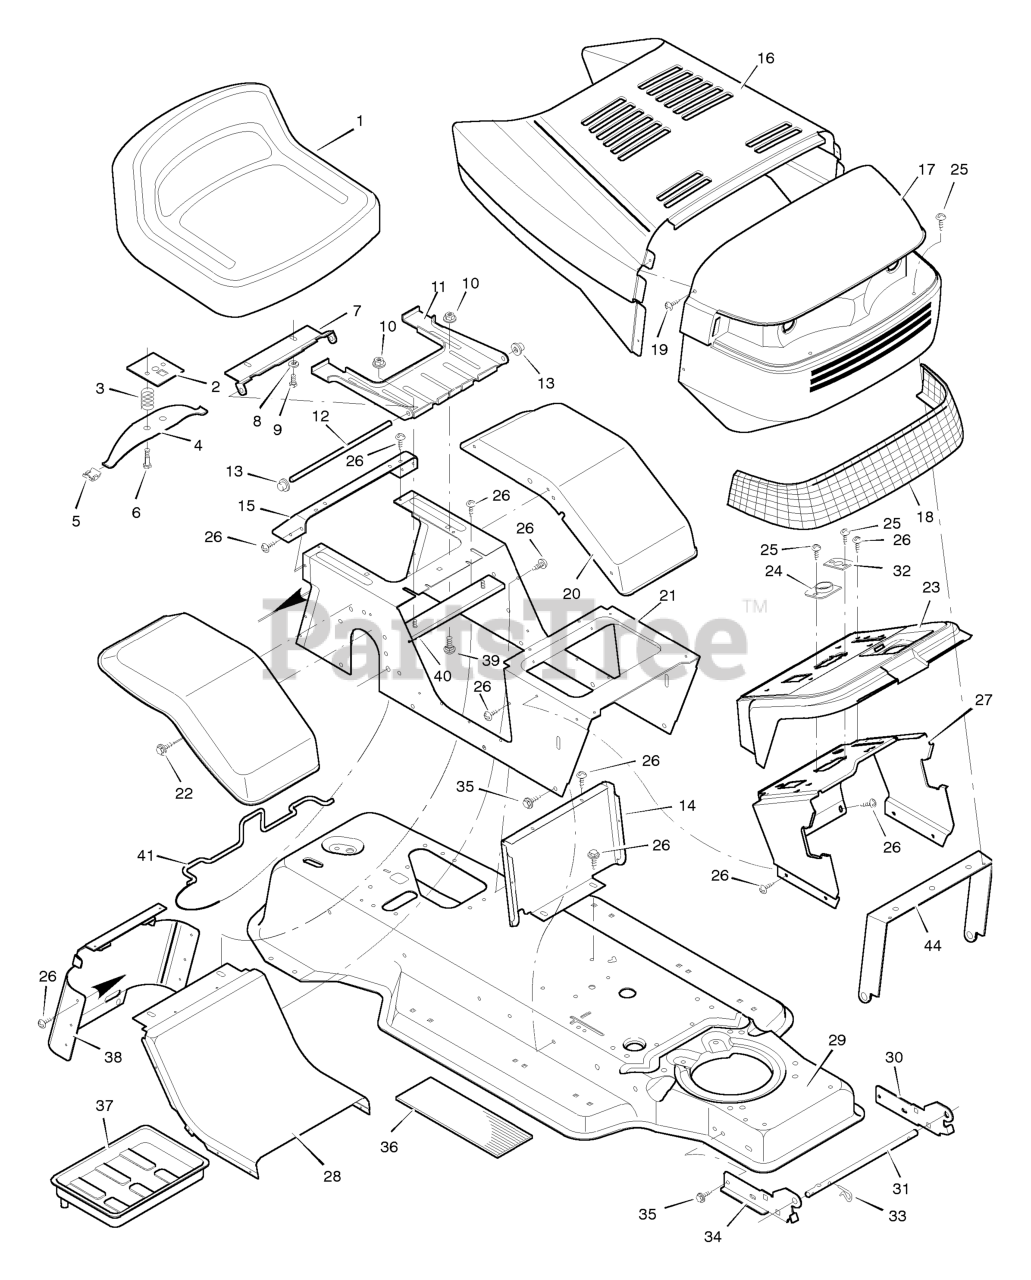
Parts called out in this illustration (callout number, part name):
2	Plate Assembly, Switch
3	Spring, Compression
4	Spring, Seat
5	Glide, Spring
6	Bolt, Shoulder
7	Support, Seat
8	Lockwasher
9	Bolt, Hex
10	Locknut, Flange
11	Bracket, Pivot
12	Rod, Pivot
13	Cap, Push On
14	Insert, Front
15	Fender, Apron
16	Hood
17	Grille Assembly
21	Console Assembly
23	Dash Panel
24	Bearing, Steering
26	Screw
27	Support, Dash
28	Insert, Rear
29	Frame Assembly
30	Bracket, Left Grille
31	Rod, Pivot
32	Bearing
33	Pin, Hair
34	Bracket, Right Grille
37	Tray, Battery
38	Cap, Console
39	Bolt
40	Channel Assembly
41	Clamp, Battery
44	Brace, Grille
46	Bolt, Hex
